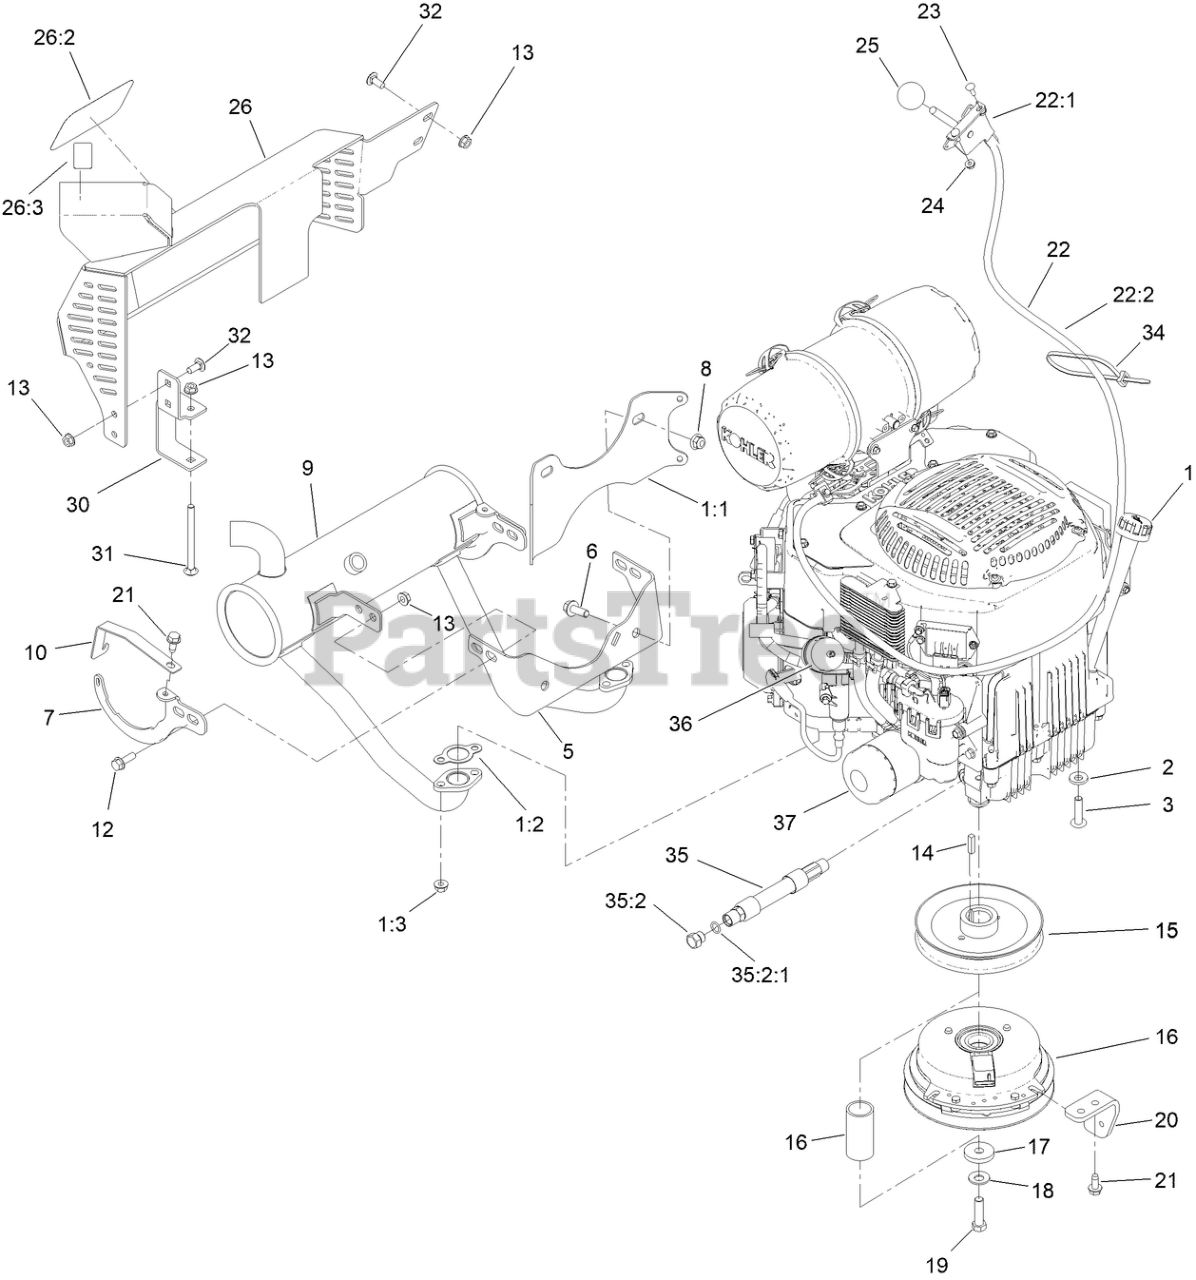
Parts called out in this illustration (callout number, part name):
1:1	BRACKET-MUFFLER
1:2	GASKET-EXHAUST
1:3	NUT-FLANGE
2	WASHER-BELLEVILLE
3	SCREW-BHTF
5	BRACKET-MUFFLER
6	SCREW-HHF
7	SUPPORT-MUFFLER
8	NUT-HF, NI
9	MUFFLER-KOHLER
10	BRACKET-MUFFLER, KOH
12	SCREW-HHF
13	NUT-HF
15	PULLEY
16	CLUTCH
17	WASHER-CLUTCH
18	WASHER-SPRING
19	SCREW-HH
20	STOP-CLUTCH
21	SCREW-HWHTF
22	THROTTLE ASM
22:1	LEVER-CONTROL
22:2	CABLE-THROTTLE
23	BOLT-CARR
24	NUT-LOCK, FLANGE
25	KNOB-BALL
26	MUFFLER GUARD ASM
26:2	DECAL
26:3	DECAL-HOT SURFACE
30	BRACKET-MOUNTING, GUARD
31	SCREW-CARR
32	SCREW-CARR
34	TIE-CABLE
35	HOSE ASM
35:2	PLUG-HH
35:2:1	O-RING
36	FILTER-FUEL
37	FILTER-OIL
